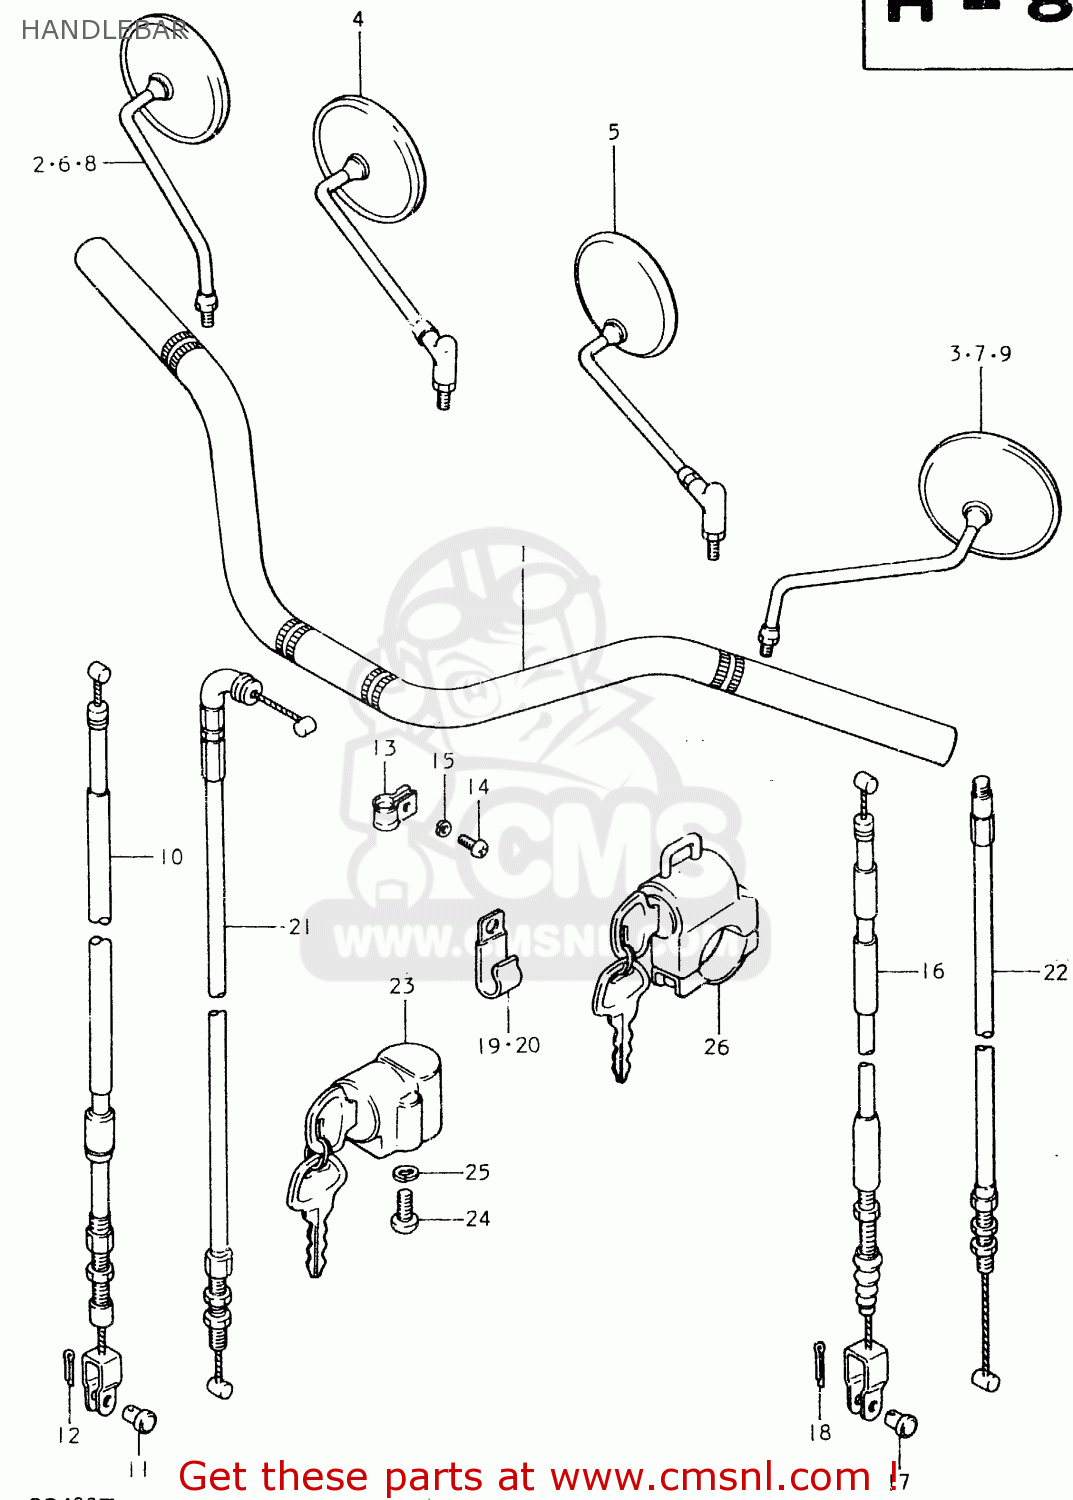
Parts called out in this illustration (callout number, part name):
1	HANDLEBAR
2	MIRROR ASSEMBLY,REAR VIEW
3	MIRROR ASSEMBLY,REAR VIEW
4	MIRROR ASSY,RH
5	MIRROR ASSY, REAR VIEW
6	MIRROR ASSY,RH
7	MIRROR ASSY,LH
8	MIRROR ASSY, REAR VIEW RH
9	MIRROR ASSY, REAR VIEW LH
10	CABLE ASSEMBLY,FRONT BRAKE
11	PIN(L:17.5)
12	PIN
13	GUIDE,CABLE
14	SCREW
15	LOCK WASHER
16	CABLE ASSEMBLY,CLUTCH
17	PIN(L:15)
18	PIN
19	CLAMP
20	CLAMP
21	CABLE ASSEMBLY,THROTTLE
22	CABLE ASSEMBLY,DECOMPRESSION
23	LOCK ASSEMBLY,STEERING
24	SCREW
25	LOCK WASHER
26	LOCK ASSEMBLY,HELMET
